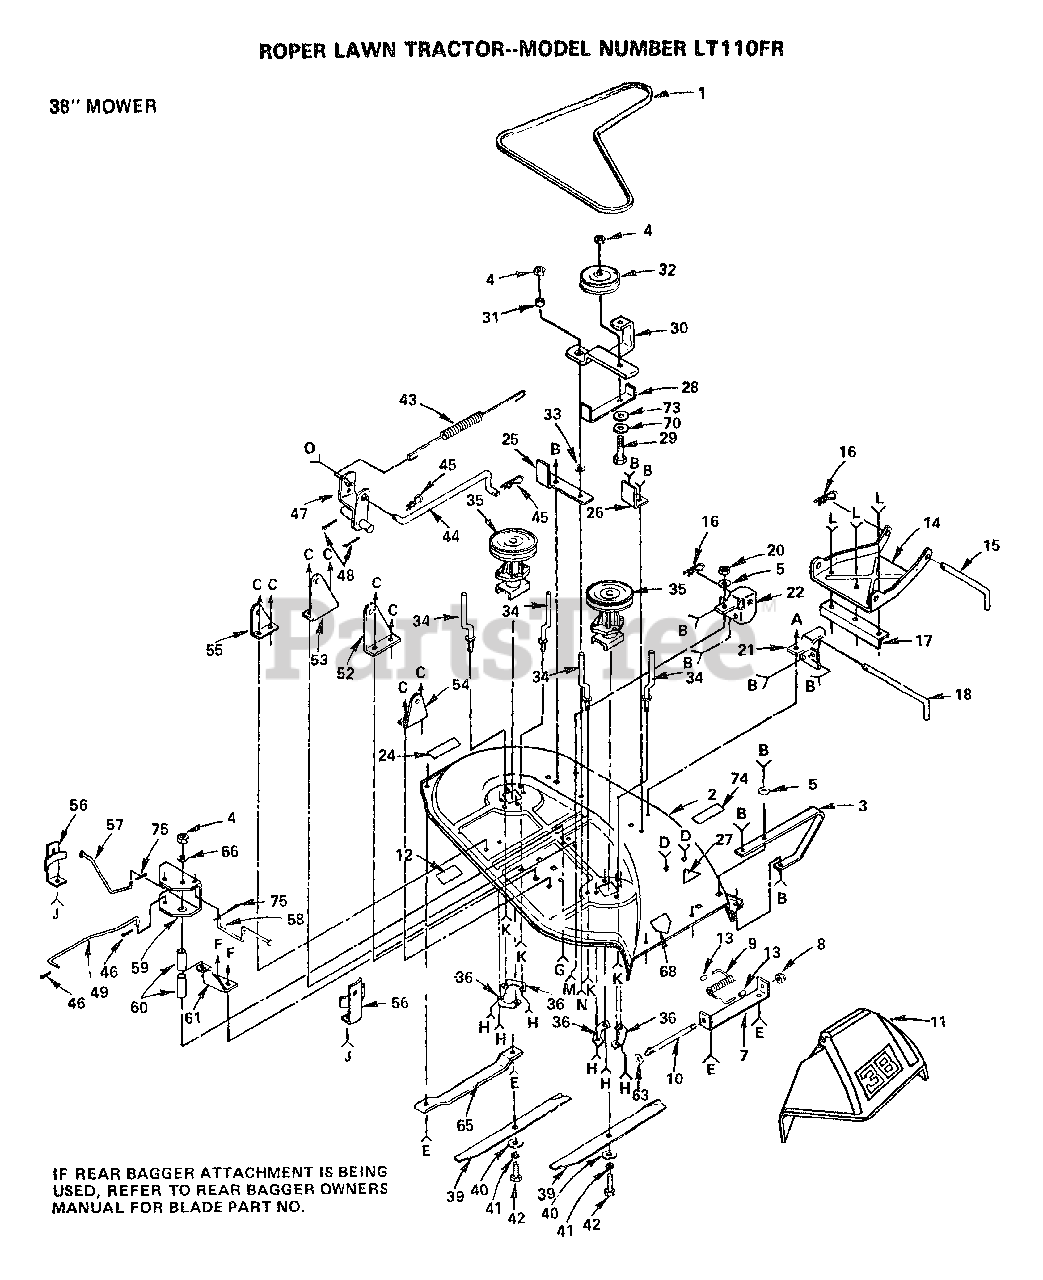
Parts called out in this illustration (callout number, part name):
1	BELT-V.79.1.MWR
5	WASHER M
10	ROD-HINGE T
11	DEFLECTOR-SHLD T
12	DECAL.LT
14	LINK.PARALLEL
15	"ROD, FRT. PARAL T"
16	RETAINER.SPRING
17	LINK STOP
24	DECAL INSTRUCTION CAUTION
27	DECAL - SAFETY STANDARD
31	SPACER RETAINER
32	IDLER-FLAT T
33	"WASHER, WEAR LT"
34	BELT KEEPER LT
36	SUPPORT PLATE LT
40	WASHER
42	BOLT.3/8-24X1-1/2
47	ROCKSHAFT T
49	ROD BRAKE LT
54	"BRKT,SUSP RH T"
55	"BRKT,SUSP REAR LH"
56	BRAKE LT
57	"ROD, BRAKE LH LT"
58	ROD BRAKE LT
59	"BRK,BRAKE,PVT LT"
60	SPACER BRAKE LTV
61	BRACKET SUPT LTV
63	WASHER
65	RUNNER-LH M
66	WASHER
70	WASHER
73	WASHER
74	DECAL.WARNING.T
